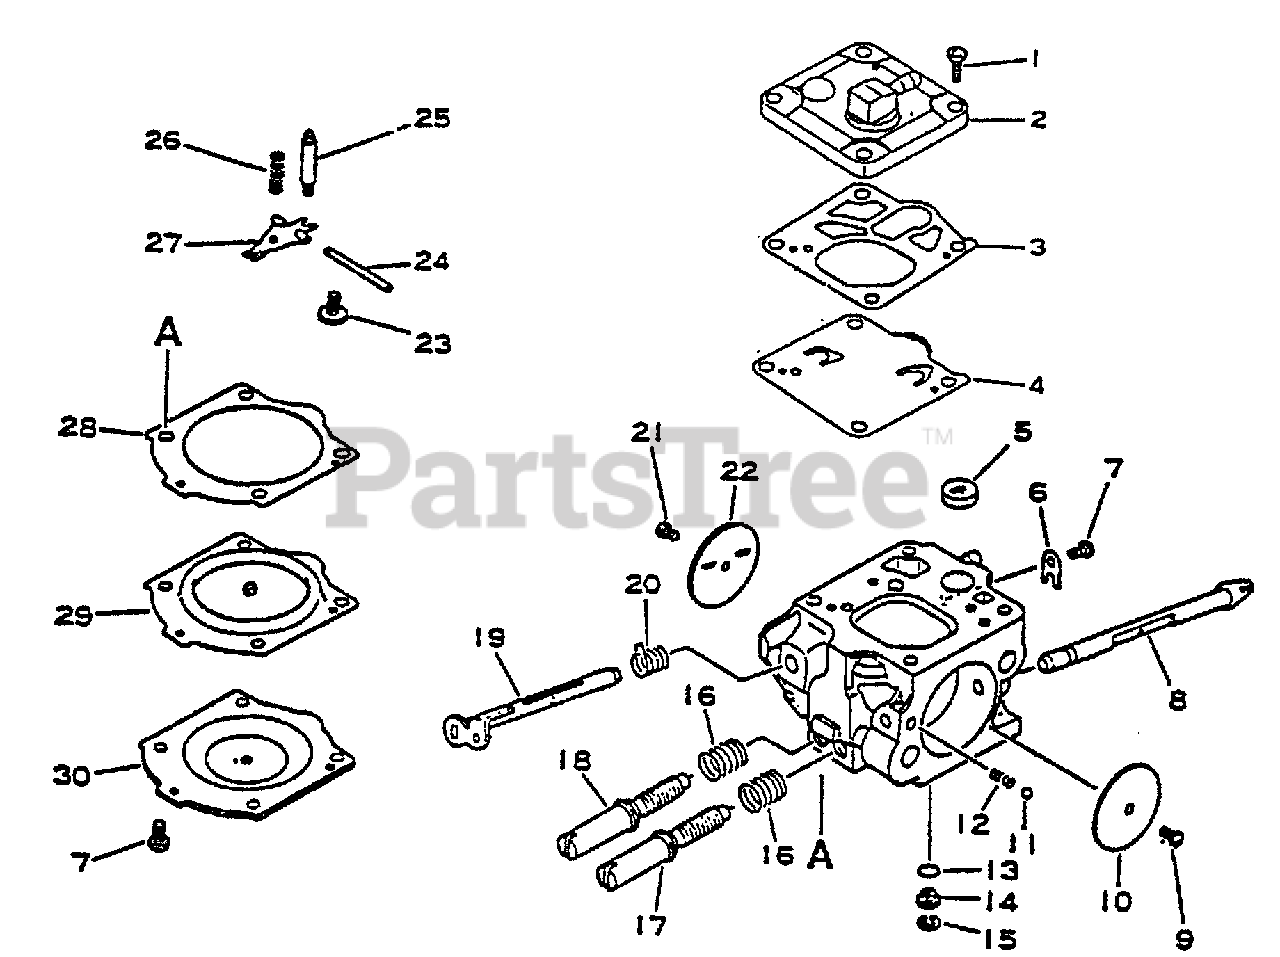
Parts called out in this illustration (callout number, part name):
1	SCREW, PUMP COVER
2	COVER, PUMP
3	GASKET, PUMP
4	DIAPHRAGM, PUMP
5	STRAINER
6	RING, RETAINING
7	SCREW
8	SHAFT, CHOKE
10	VALVE, CHOKE
11	BALL, CHOKE
12	SPRING
13	O-RING
14	JET - 42
15	WASHER
16	SPRING
17	NEEDLE - HIGH SPEED
18	NEEDLE - LOW SPEED
19	SHAFT, THROTTLE
20	SPRING, THROTTLE RETURN
21	SCREW
22	VALVE, THROTTLE
23	SCREW, METERING LEVER PIN
24	PIN, METERING LEVER
25	VALVE, INLET NEEDLE
26	SPRING, METERING LEVER
27	LEVER, METERING
28	GASKET, METERING
29	DIAPHRAGM, METERING
30	COVER, METERING
